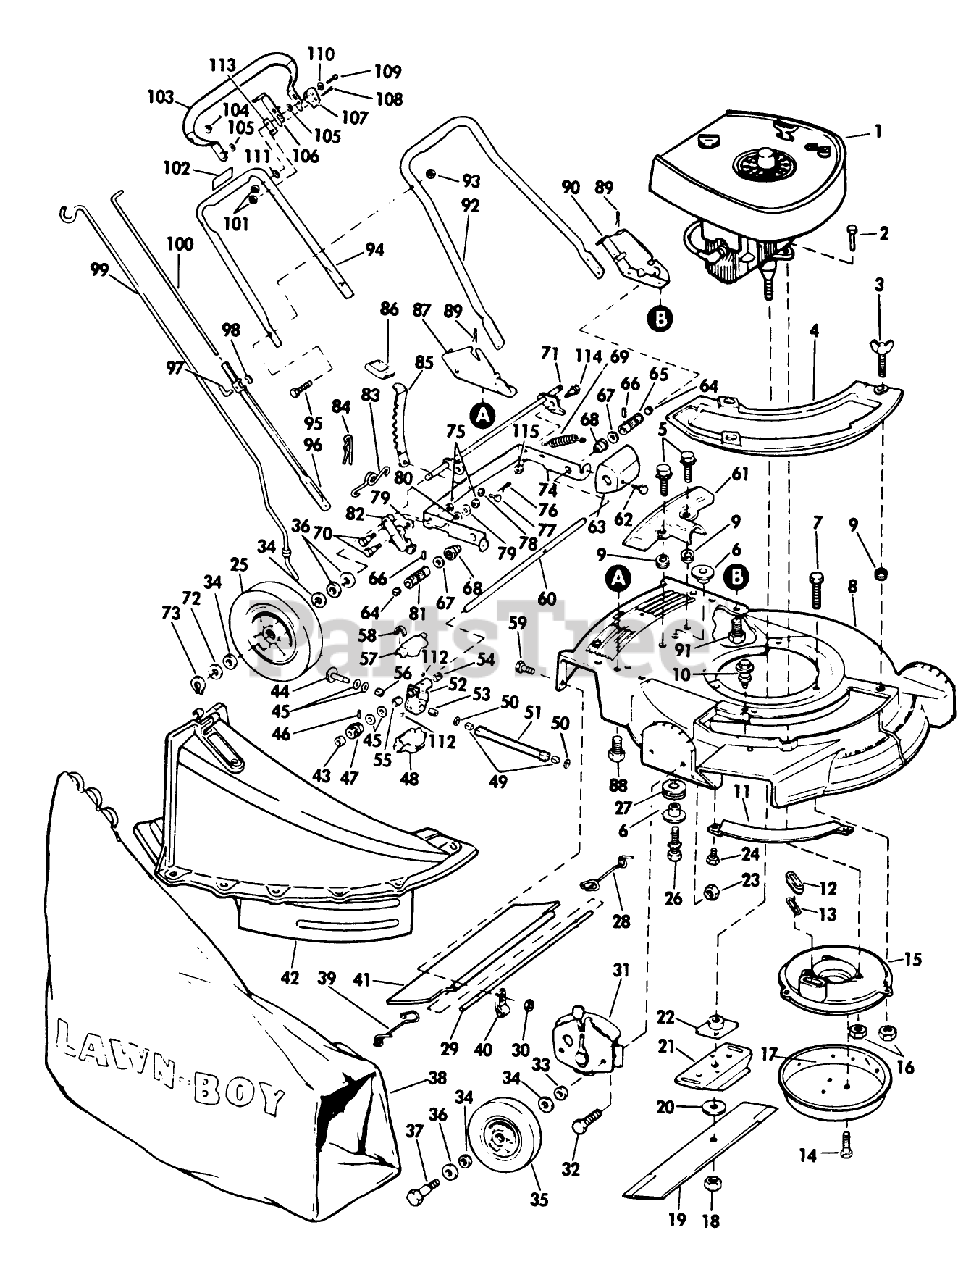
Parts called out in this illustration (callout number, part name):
2	BOLT F
3	WING SCREW LAWRE
5	SCREW SEMS TRM HEX HD
6	SPACER ECK PRES
7	SCREW V
11	BAR-TOE
12	SLEEVE
13	GASKET S
16	NUT-LOCK F
18	NUT-BLADE
20	WASHER
22	PLATE AND COLLAR ASM
23	NUT-LOCK F
27	GROMMET
28	SPRIG T/SHLD ASOC
29	ROD 21" ADVANCE
30	LOCKNUT E
33	WASHER WROUGHT
34	WASHER
35	WHEEL & TIRE KIT
36	SPACER
37	BOLT WHEEL
38	89802 LB WHOLE GOODS
39	SPRING;TRAILING SHIELD RH
40	CLAMP ROD KMC
43	WASHER
45	THRUST WASHER
46	ROLL PIN
49	BUSHING
50	O Ring
56	NEEDLE BEARING
57	GEAR COVER UPPER
60	DRIVE SHFT TAG AY
61	COVER
63	GUARD
64	Plug
66	PIN
69	SPRING
70	BOLT RB&W
72	SPACER
73	RET RING
75	STOP NUT
77	PIN
78	WASHER SPRING LAR
79	WASHER S
83	SPRING N.A.S
85	LEVER
86	KNOB
88	SCREW
89	HAIR PIN
91	SCREW
93	LOCKNUT E
95	SCREW
99	ROD GRASSBAG
100	ROD CONTROL
101	LOCKNUT E
105	WASHER M
106	LEVER LOCKOUT
108	SCREW-HANDLE STOP
109	BOLT PIONEER
111	WASHER
112	**FITTING LINCOLN
113	HANDLE STOP
114	BOLT RB&W
115	LOCKNUT E
